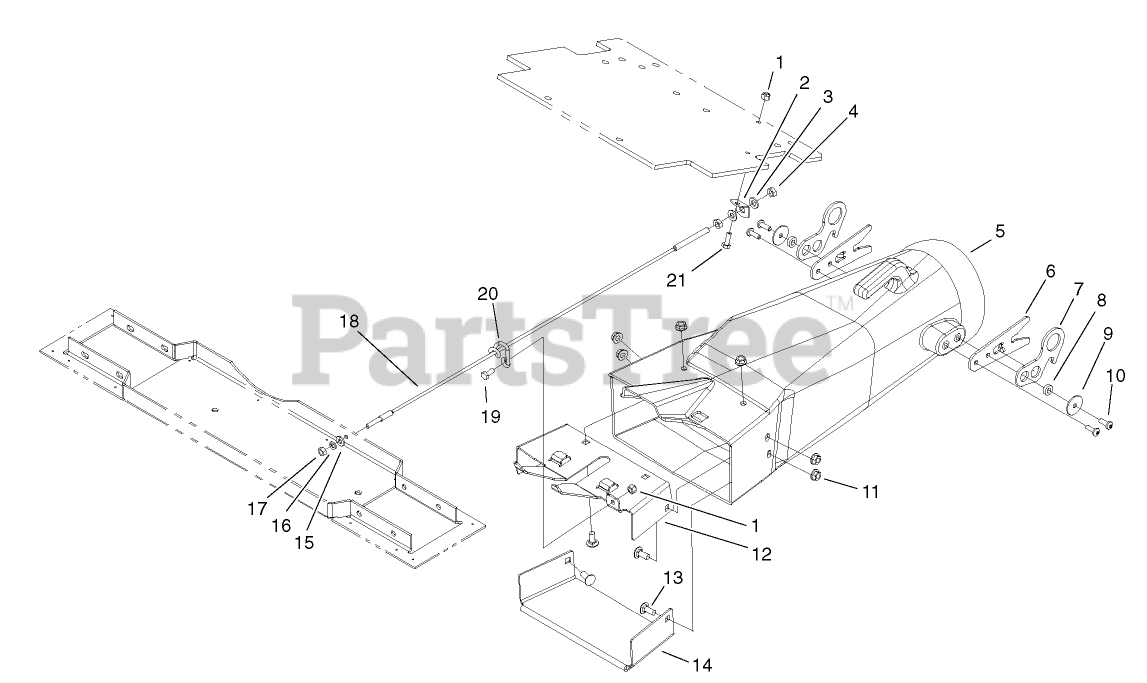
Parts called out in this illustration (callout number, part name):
1	NUT-LOCK, NI
2	BRACKET-SPRING
3	WASHER-PLAIN
4	NUT-JAM
5	PLENUM
6	PLATE-GUIDE
7	PLATE-LATCH
8	SPACER
9	WASHER-FLAT
10	SCREW-TORX
11	NUT-HF
12	PLATE-PLENUM, TOP
13	SCREW-CARR
14	PLATE-PLENUM, BOTTOM
15	WASHER-FLAT
16	WASHER-LOCK
17	NUT-HEX
18	CABLE-TENSION
19	SCREW-HH
20	GUIDE-CABLE
21	SCREW-HH
